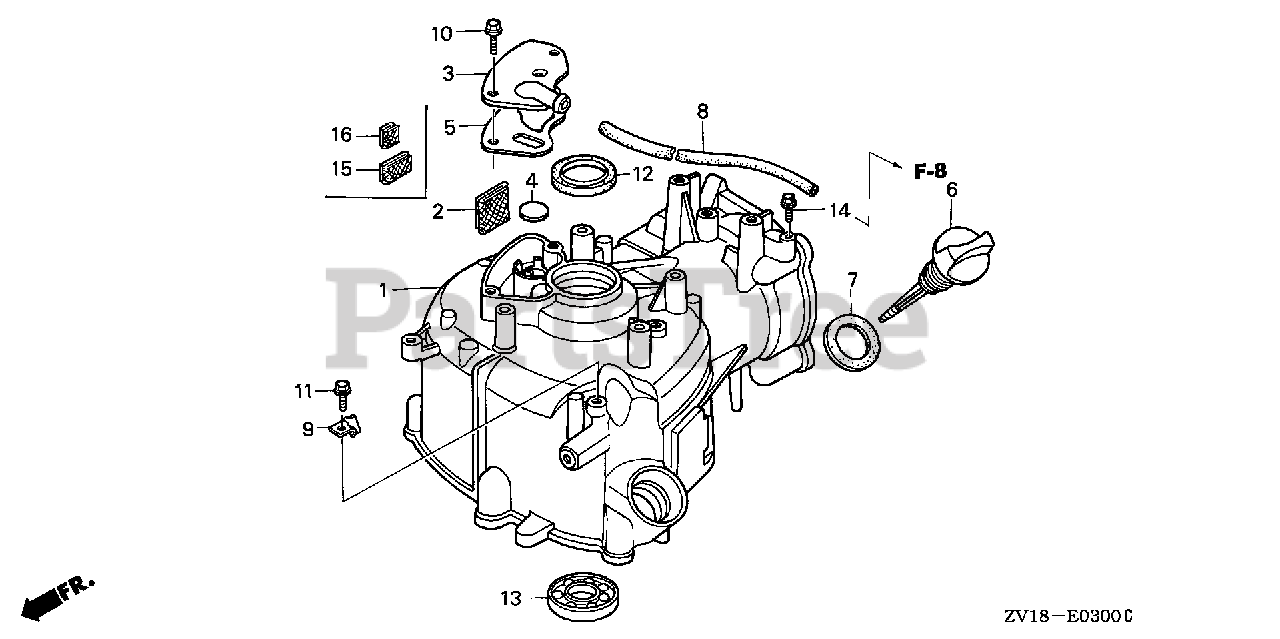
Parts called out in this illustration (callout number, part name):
1	CYLINDER ASSY. *NH8* (DARK GRAY)
3	CAP, BREATHER CHAMBER
4	VALVE, BREATHER
5	GASKET, BREATHER CAP
6	CAP, OIL FILLER
7	GASKET, OIL FILLER CAP
8	TUBE, BREATHER
9	CLAMP, BREATHER TUBE
10	BOLT, FLANGE (6X12) (CT200)
11	BOLT, FLANGE (5X10) (CT200)
12	OIL SEAL (25X38X7)
12	OIL SEAL (25X38X7) (ARAI)
13	BEARING, RADIAL BALL (6205)
14	BOLT, FLANGE (5X10) (CT200)
15	FILTER A, BREATHER
16	FILTER B, BREATHER
